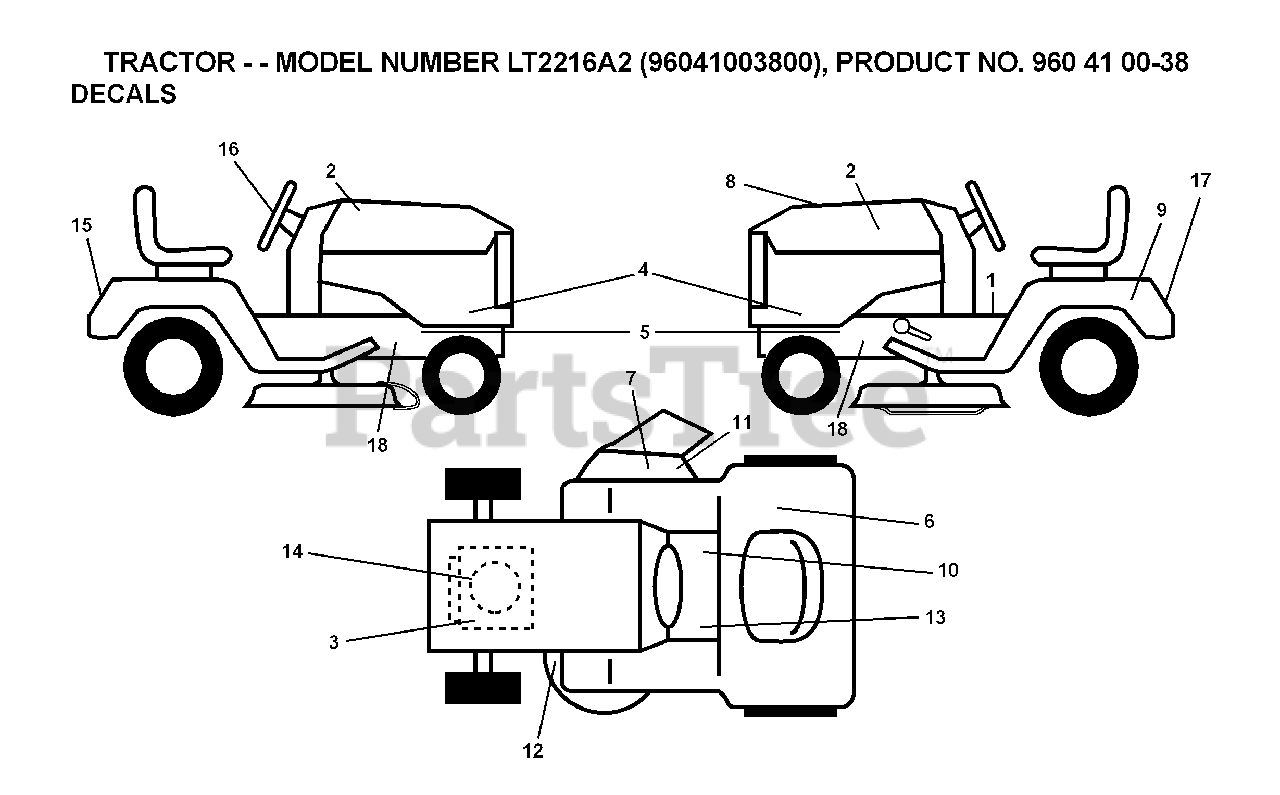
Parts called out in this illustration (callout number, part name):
7	DECAL.INTERNATIONL.CUTFINGER
9	DECAL BTRY SYMBOLS
10	DECAL PARK BRAKE
11	DECAL, DEFLECT WARNING
12	DECAL V BELT SCHEMATIC
